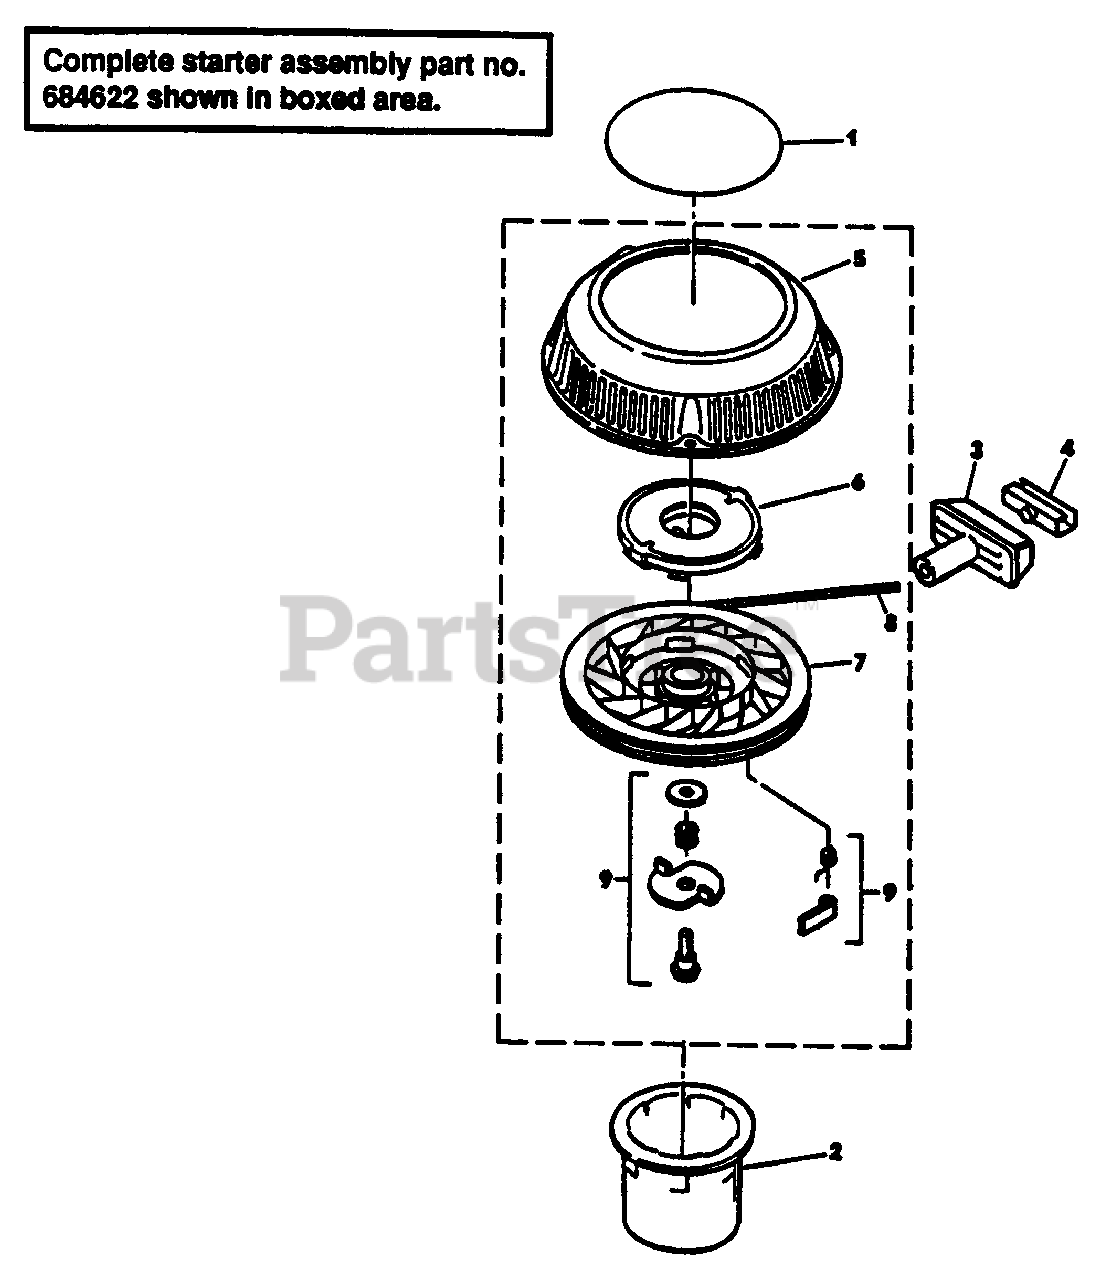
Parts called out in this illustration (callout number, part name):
1	Decal
2	Starter Hub
3	Starter Handle
4	Clip-Rope Insert
5	Starter Housing & Shaft
6	Recoil Spring & Keeper
7	Pulley
8	Rope
9	Dog Kit Assembly
